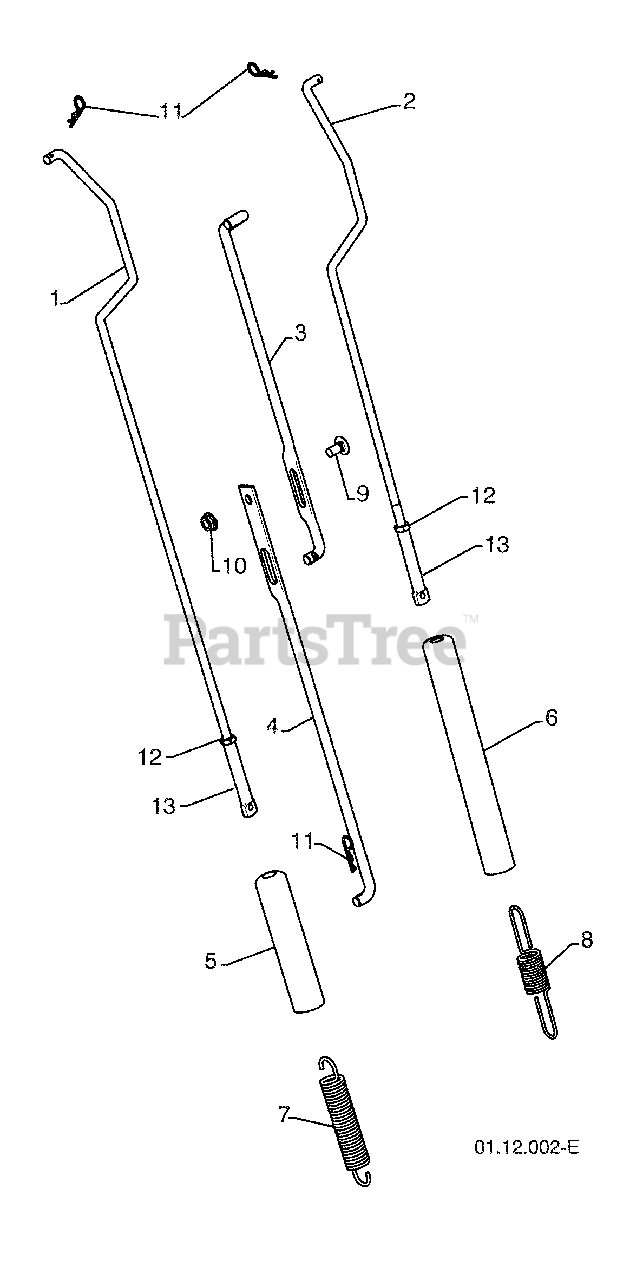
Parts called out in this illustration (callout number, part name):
1	IMPELLER ROD ASSEMBLY
2	TRACTION ROD ASSEMBLY
3	SHIFTER ROD TOP
4	SHIFTER ROD BOTTO
5	SPRING SLEEVE
6	SPRING SLEEVE
7	IMPELLER SPRING
8	TRACTION SPRING
9	CARRIAGE BOLT 5/16-18 X .750
10	NUT 5/16-18
12	5/16-18 JAM NUT
13	CONTROL ROD END
